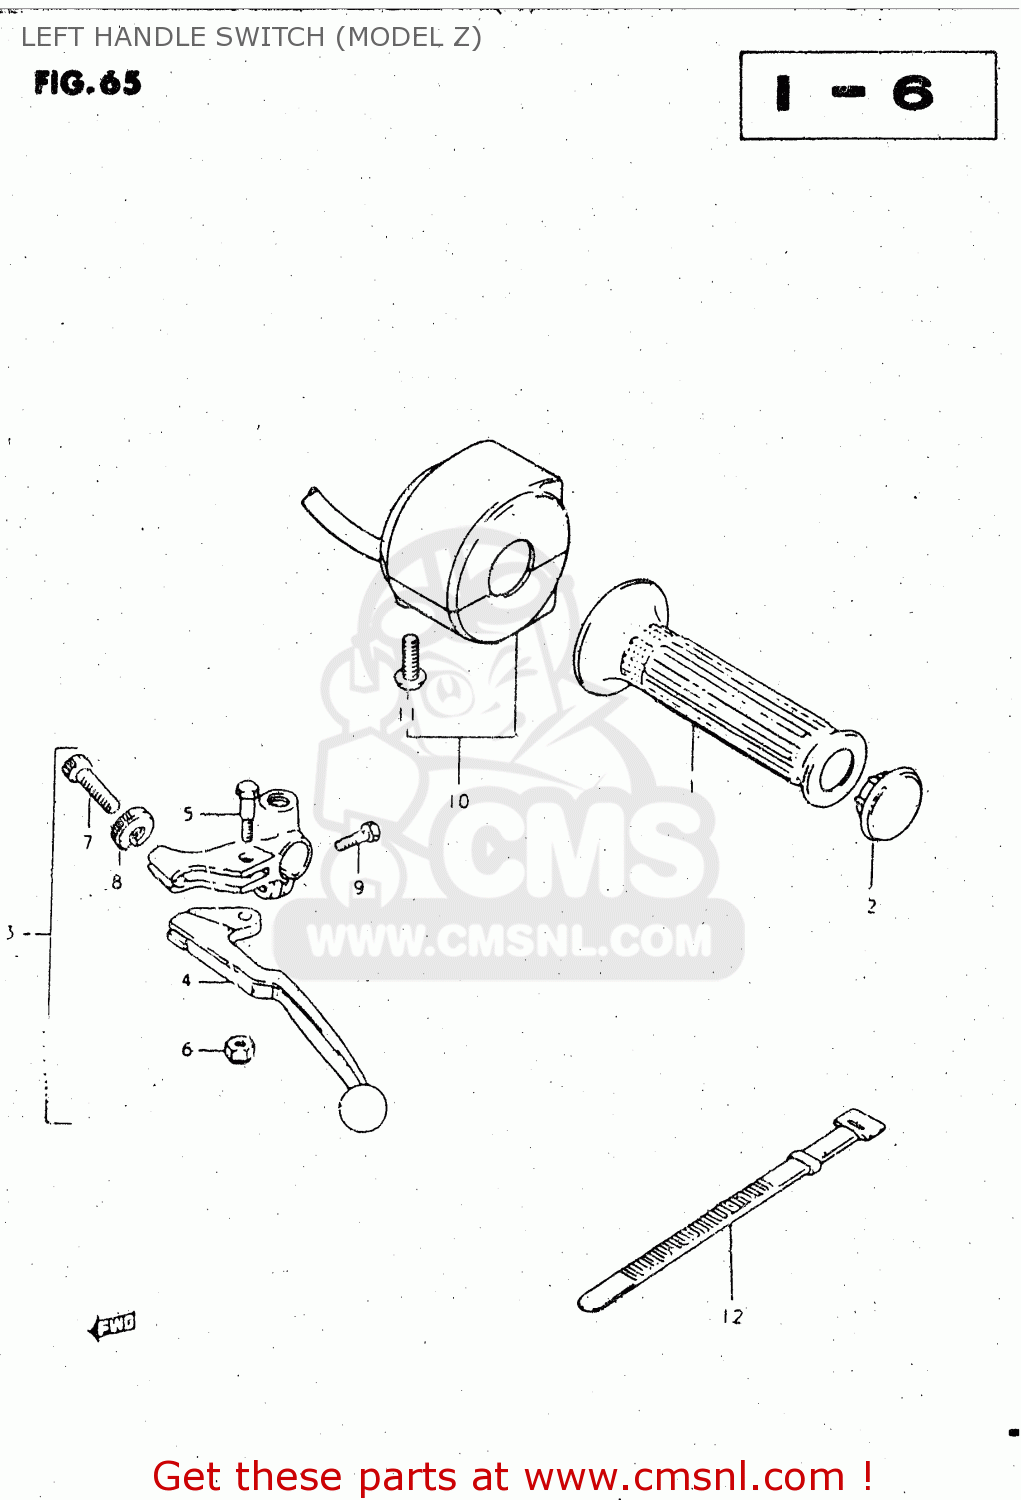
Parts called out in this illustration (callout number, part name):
1	GRIP,LEFT
2	CAP,GRIP END
3	LEVER ASSEMBLY
4	LEVER,CLUTCH
5	BOLT,LEVER
6	NUT 6MM
7	ADJUSTER,CABLE
8	NUT,CABLE ADJUSTER
9	BOLT
10	SWITCH ASSY, HANDLE LH
11	SCREW
12	CLAMP(L:120)
